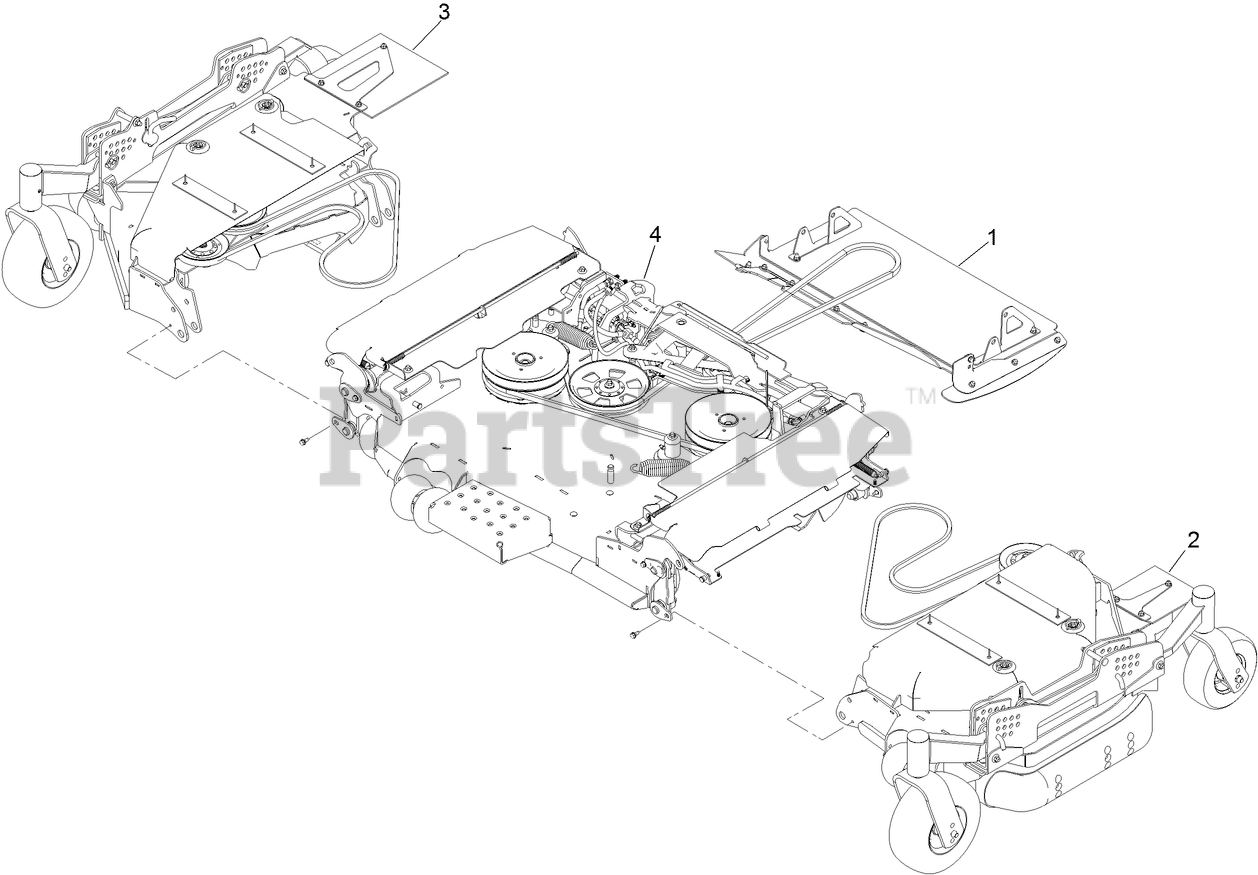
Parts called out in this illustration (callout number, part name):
2	ASM-DECK, LH WING [GAS]
3	ASM-DECK, RH WING [GAS]
4	ASM-DECK, CTR 96 [TORO]
